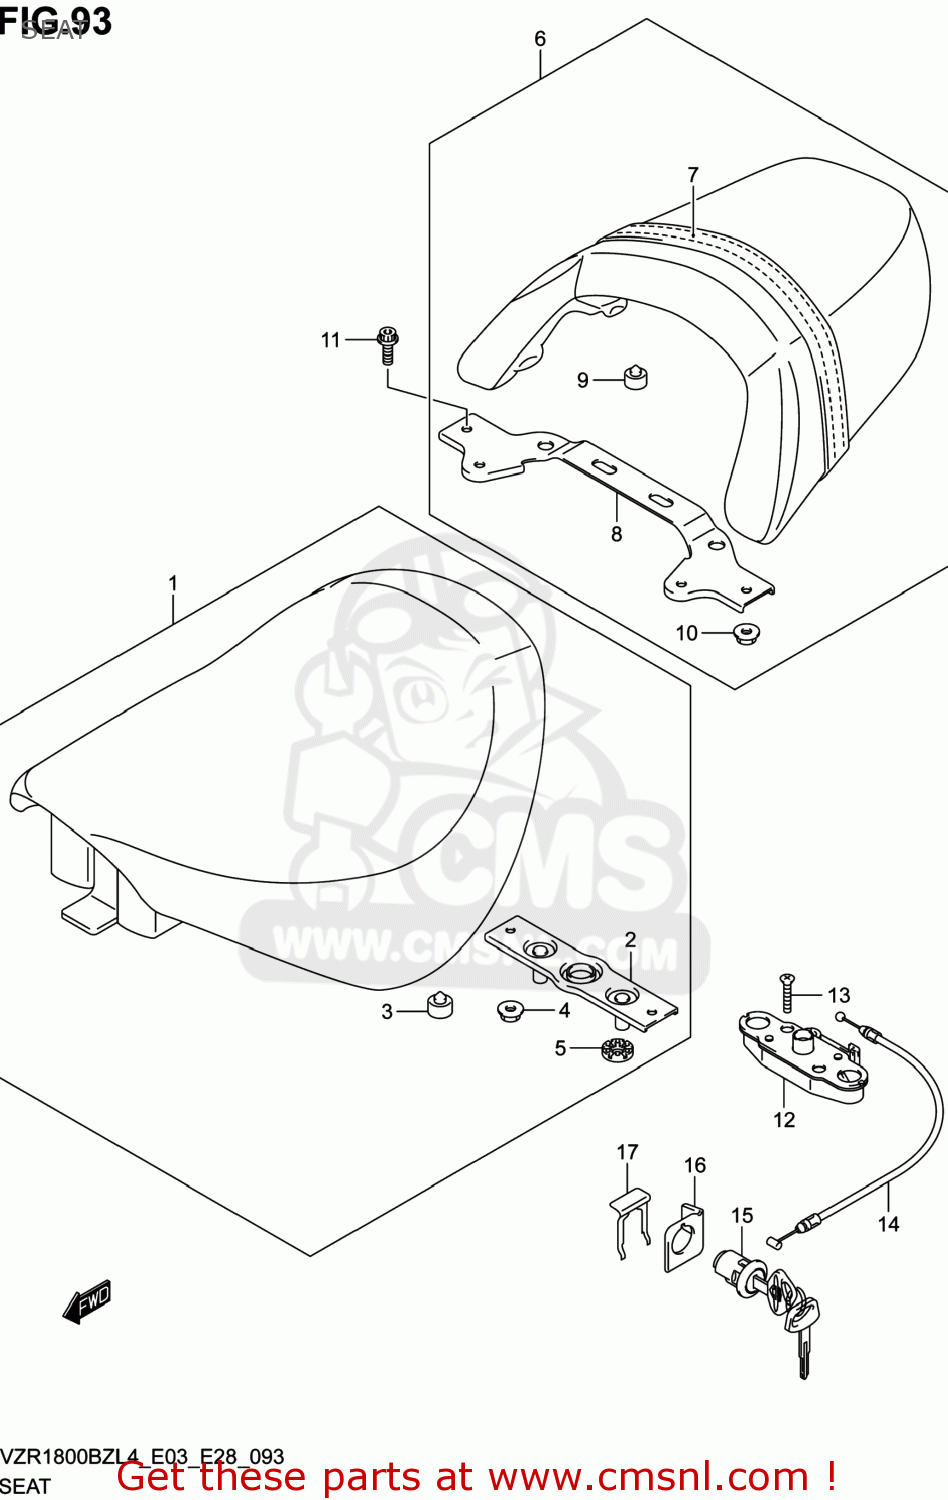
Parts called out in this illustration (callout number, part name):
1	SEAT ASSY
2	STRIKER,SEAT LOCK
3	CUSHION
4	NUT
5	CUSHION
6	SEAT ASSY,PILLION
7	BAND ASSY
8	BRACKET,BAND
9	CUSHION
10	NUT
11	BOLT
12	BRACKET,SEAT SUPPORT
13	SCREW
14	CABLE,SEAT LOCK
15	LOCK SET,SEAT
16	GUIDE,SEAT LOCK CABLE
17	PLATE,SEAT LOCK ASSY
